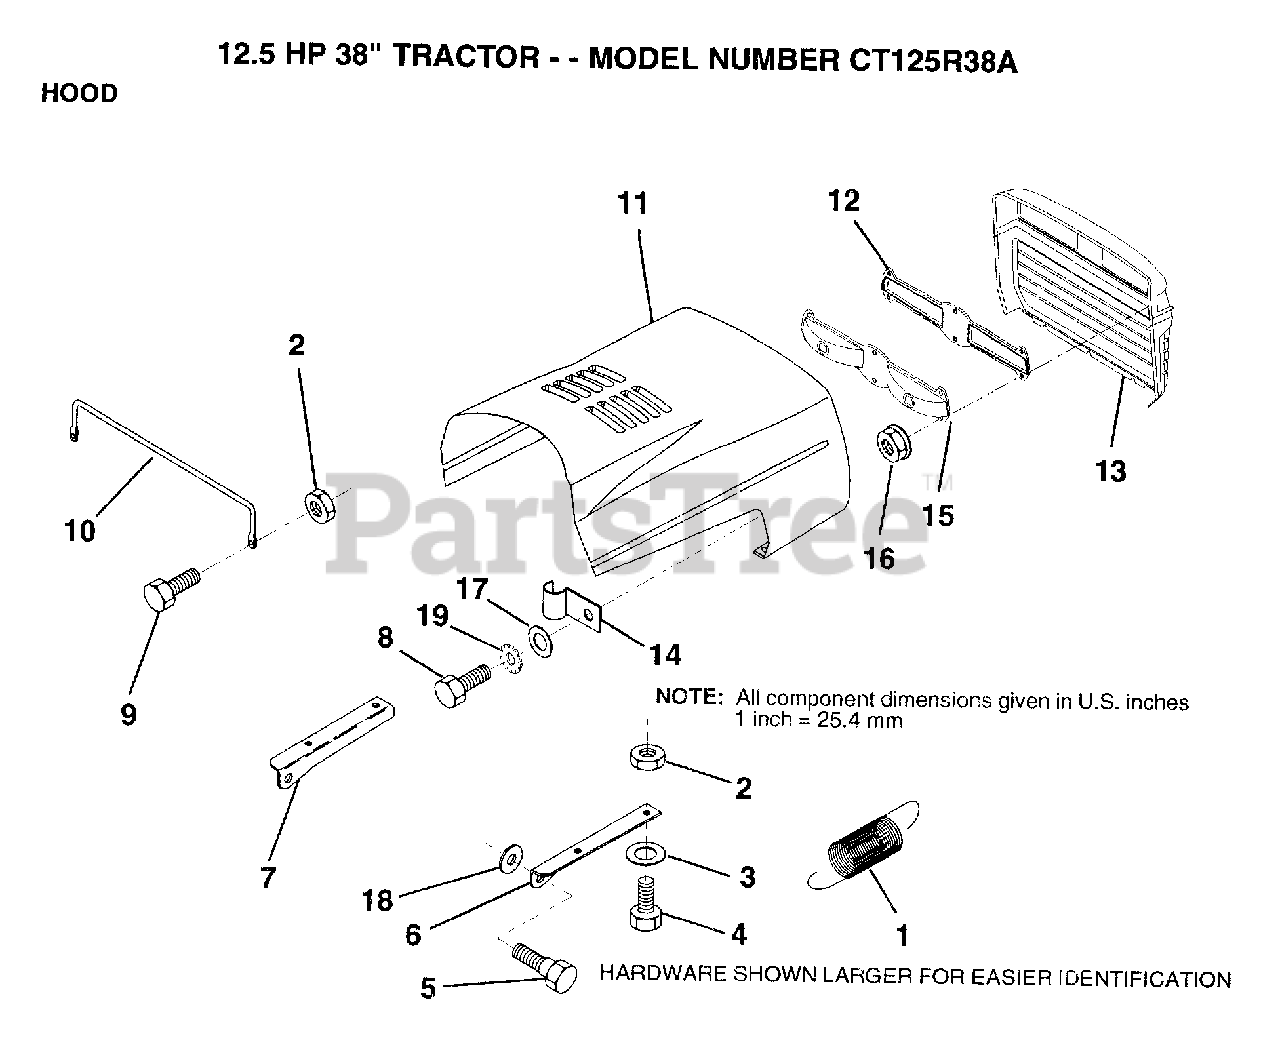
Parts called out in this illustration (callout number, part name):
1	EXT SPRING
2	NUT
3	WASHER
4	BOLT
6	BRKT HOOD RH
7	BRKT HOOD LH
10	"BRACE,HOOD"
14	CLIP T
16	NUT
17	WASHER PM
18	WASHER
19	LOCKWASHER GT
